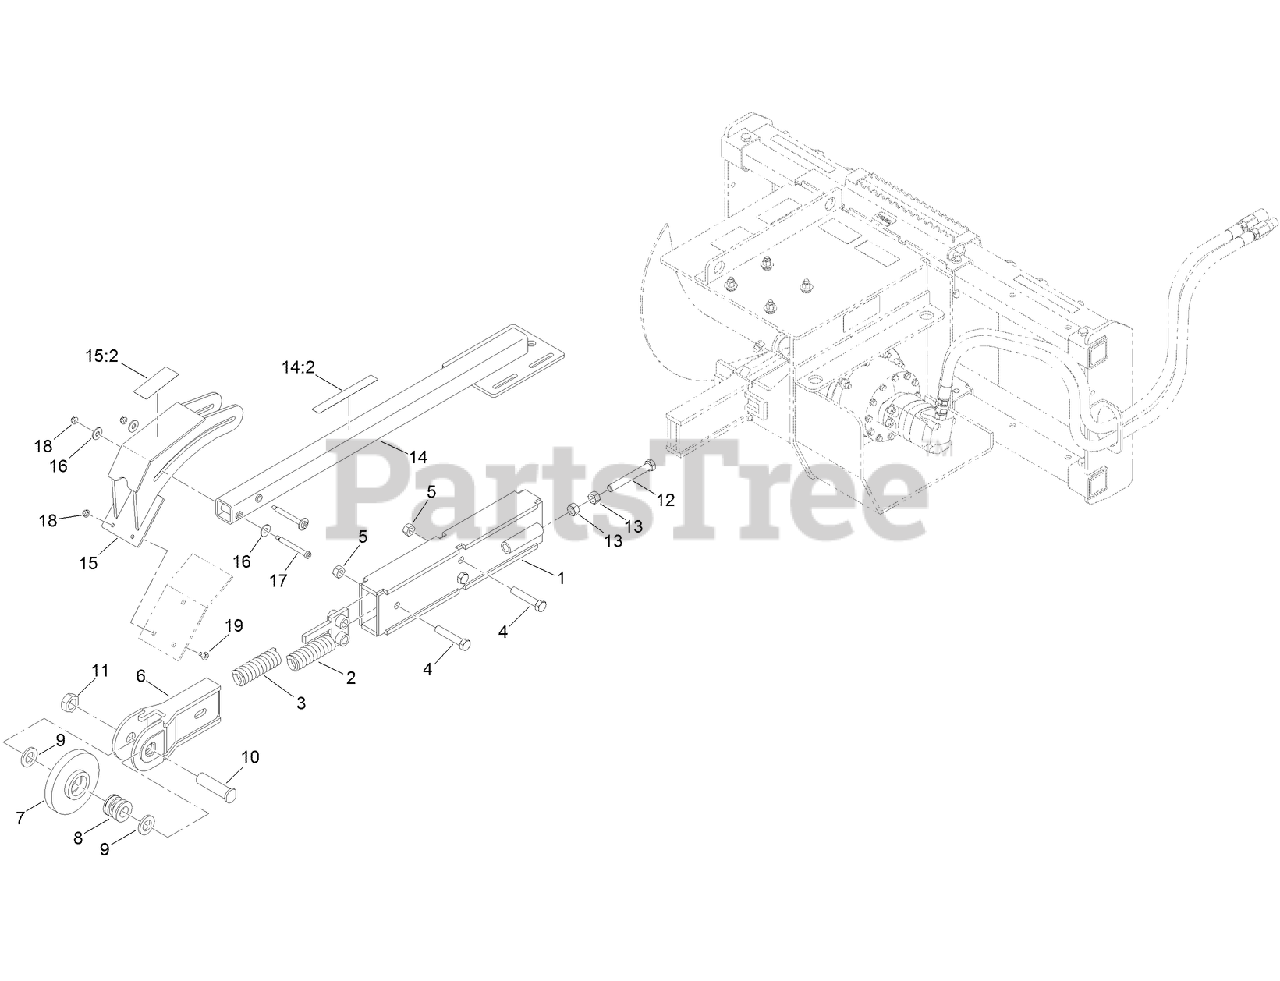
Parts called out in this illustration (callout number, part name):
1	ARM-BOOM
2	GUIDE-SPRING, TRENCHER
3	SPRING-COMPRESSION
4	SCREW-HH
5	NUT-LOCK
6	MOUNT-WHEEL, IDLER
7	WHEEL-IDLER
8	BEARING
9	SPACER
10	SHAFT-IDLER
11	NUT-LOCK, NI
13	NUT-HEX
14	CRUMBER ARM ASM
14:2	DECAL-DANGER
15	CRUMBER ASM
15:2	DECAL-DANGER
16	WASHER-FLAT
18	NUT-HF, NI
19	SCREW-HH
